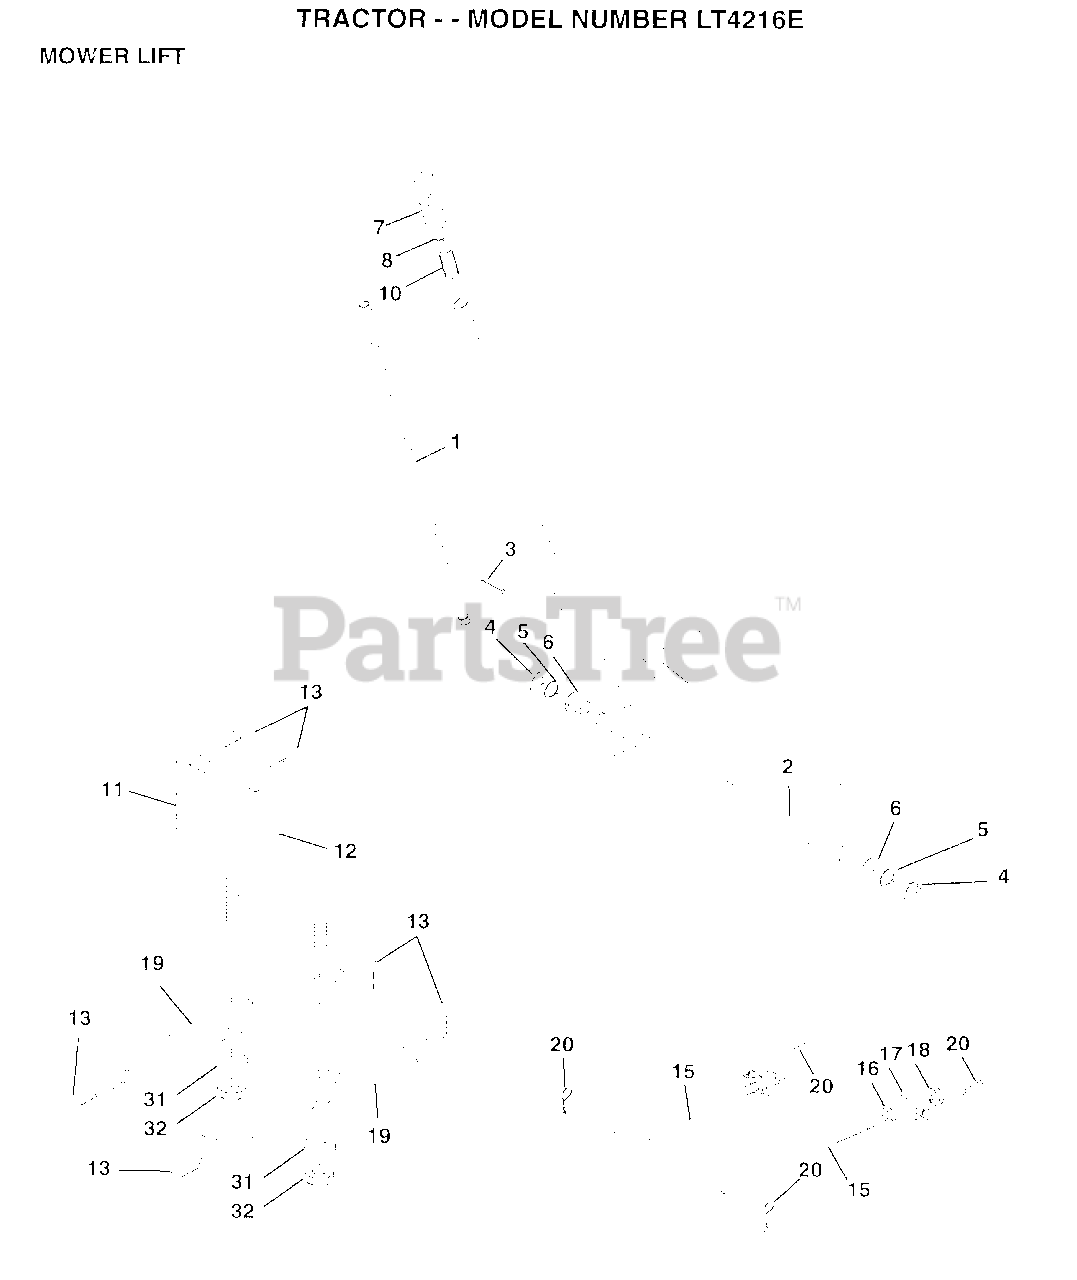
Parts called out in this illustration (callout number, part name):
1	WIRE ASM
2	HANDLE.LIFT.LH.
3	PIN GROOVE
5	WASHER
6	NYLON BEARING
7	GRIP
15	LINK.FRONT
16	NUT
17	TRUNION
18	NUT.LK.W/WSH.1/2.
19	ARM SUSP REAR
20	RETAINER.SPRING
31	BEARING PVT LH
32	NUT.CROWNLOCK.3/8
